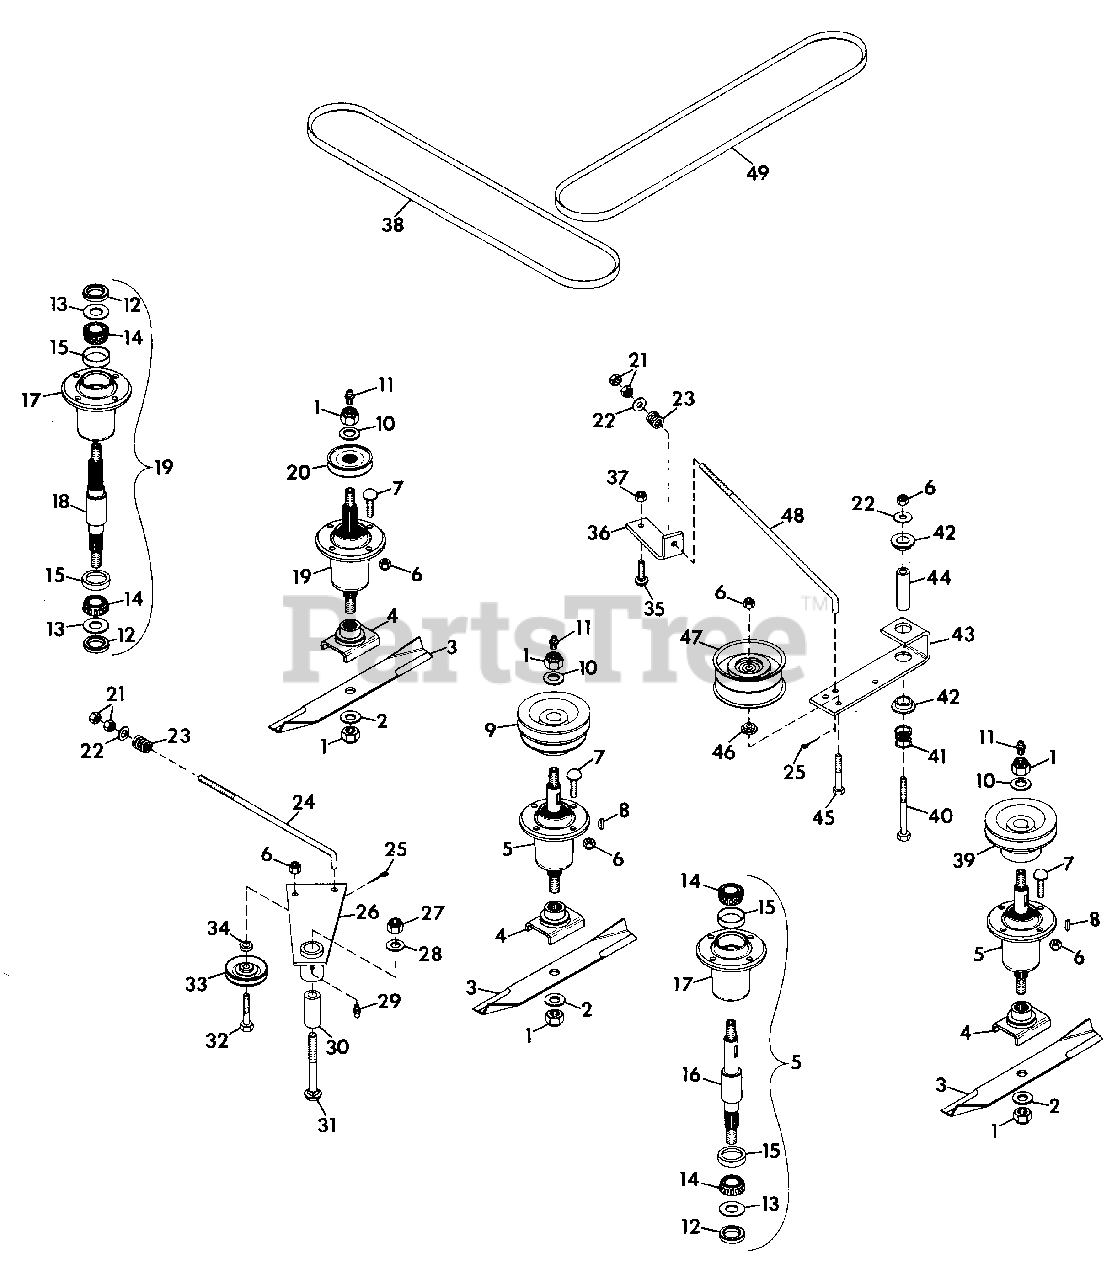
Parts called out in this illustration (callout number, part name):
1	NUT, LOCK 5/8-11
2	WASHER, FLAT .656X1.312X.095
3	BLADE
4	WELDMENT, BLADE CRADLE
5	ASSEMBLY, SPINDLE
6	NUT, LOCK 3/8-16
7	BOLT, 3/8-16X1.25 RD HD SQ NK
8	KEY, WOODRUFF .250X1 HARD
9	SHEAVE, SPINDLE
10	WASHER, FLAT .687X1.312X.130
11	FITTING, LUBE 1/8 NPT
12	SEAL, STEEL(IN 34605)
12	SEAL, STEEL(IN 21306)
13	WASHER, FLAT .975X.970X.030(IN 34605)
13	WASHER, FLAT .975X.970X.030(IN 21306)
14	CONE, ROLLER BEARING
15	CUP, ROLLER BEARING
16	SHAFT, SPINDLE
17	HOUSING, SHAFT
18	SHAFT, SPINDLE
19	ASSEMBLY, SPINDLE
20	SHEAVE, SPINDLE
21	NUT, HEX 3/8-16
22	WASHER, FLAT .406X.812X.065
23	SPRING, COMP. 1X.78
24	ROD, R.H. IDLER
25	PIN, COTTER .094X.625
26	WELDMENT, IDLER PIVOT
27	NUT, LOCK 1/2-13
28	WASHER, FLAT .500X1.250X.083
29	FITTING, LUBE 1/4-28
30	SPACER, .850X.546X2.18
31	BOLT, 1/2-13X3.50 RD HD SQ NK
32	BOLT, HEX 3/8-16X2.00
33	PULLEY
34	SPACER, IDLER .406X.750X.188
35	BOLT, 5/16-18X1.00 RD HD SQ NK
36	BRACKET, BELT TENSIONER
37	NUT, LOCK 5/16-18
38	BELT, MOWER A44
39	SHEAVE, SPINDLE
40	BOLT, HEX 3/8-16X3.25
41	SPRING, COMP. 1X.80
42	BUSHING, NYLON .76X1X.6
43	ARM, IDLER PIVOT
44	SPACER
45	BOLT, HEX 3/8-16X2.25
46	BUSHING, REAR FENDER
47	PULLEY, IDLER
48	ROD, IDLER
49	BELT, MOWER A89
